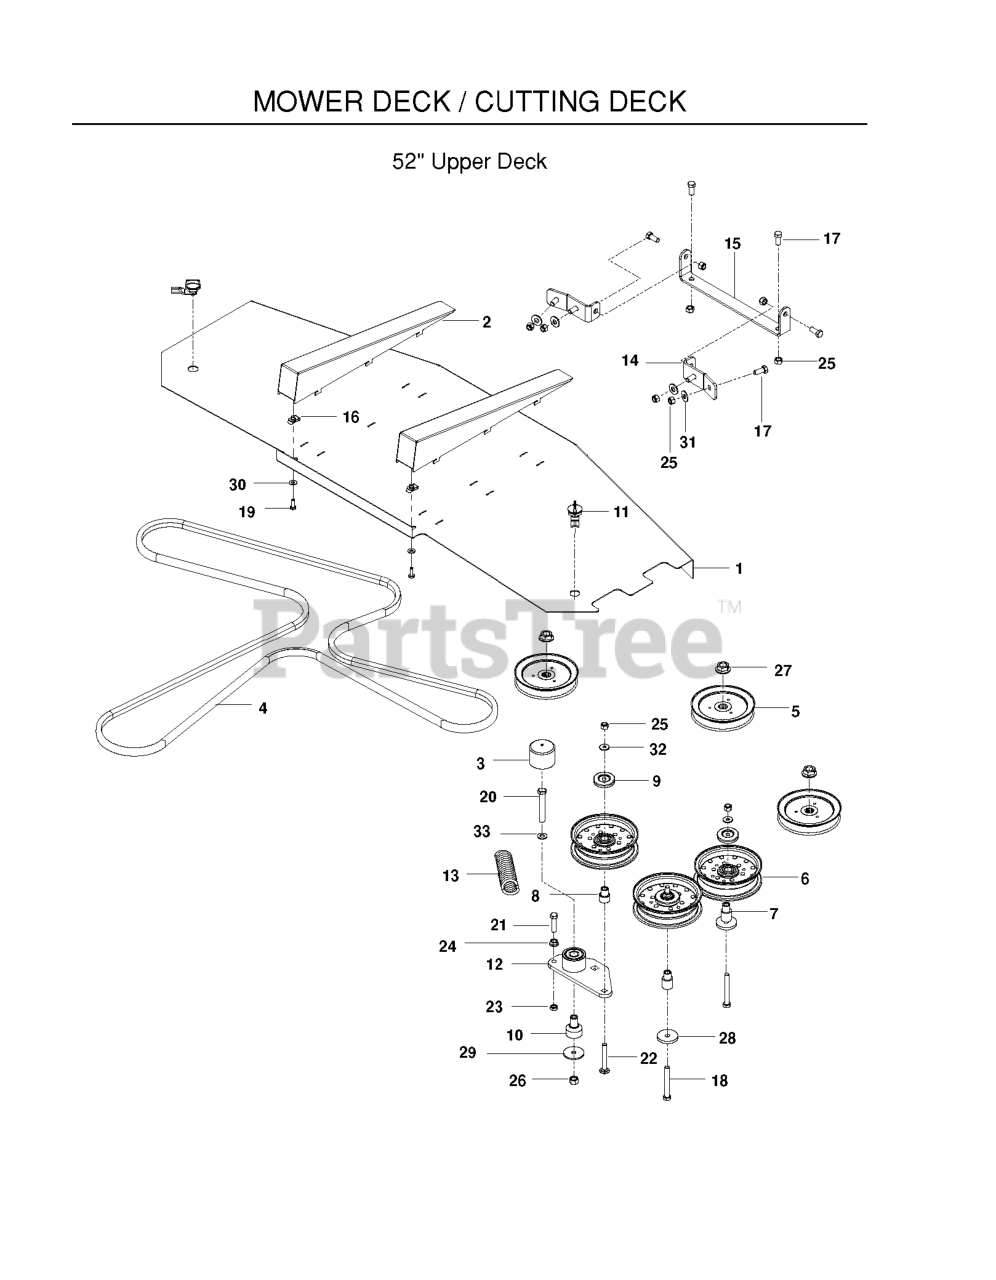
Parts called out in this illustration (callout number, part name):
1	COVER - BELT, 52 PAINTED
2	WEDGE - PAINTED
3	CAP, VINYL
4	V-BELT 142
5	PULLEY - 6.57
6	IDLER PULLEY
7	IDLER BUSHING
8	BUSHING, IDLER
9	DUST SHIELD
10	PIVOT, BEARING
11	LATCH, SHORT WING
12	ARM-IDLER W/BRG
14	HINGE, BIN
15	BASE HINGE - PAINTED
16	1/4C - U TYPE RETAINER
17	HCS 3/8-16 X 7/8 GR 5 ZD
18	HCS 3/8C X 3
19	HCS 1/4C X 3/4 HCS
20	HCS 1/2C X 3 1/4
21	HCS 3/8-16 X 1-1/2
22	RHSNB 3/8-16 X 2.75
23	NUT 3/8-16 HEX JAM
24	NUT 3/8C WHIZ
25	NUT 3/8-16 NYLOC
26	NUT 1/2-13 HEX NYLOC ZD
27	NUT FLANGE 3/4-16
28	SPINDLE WASHER
29	WASHER, SUPPORT
30	WASHER 1/4 SAE
31	WASHER 3/8 FLAT
32	WASHER, 3/8 THICK
33	CONTACT BELLSPR 1/2
